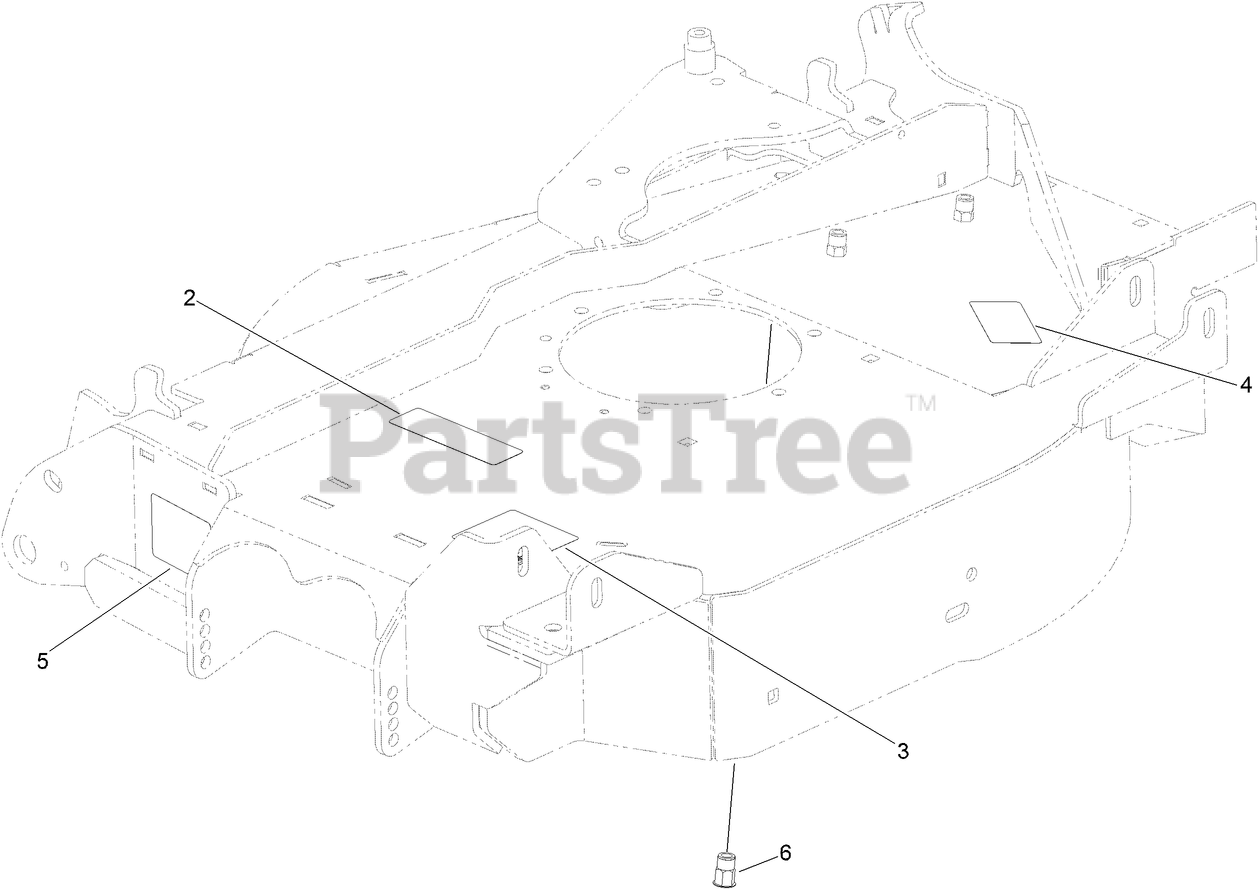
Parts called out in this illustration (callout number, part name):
2	DECAL-COVER, MISSING
3	DECAL-DANGER, THROWN OBJECT
4	DECAL-BOLT TORQUE
5	DECAL-WARNING, PINCH POINT
6	NUT-CLINCH,HEX
